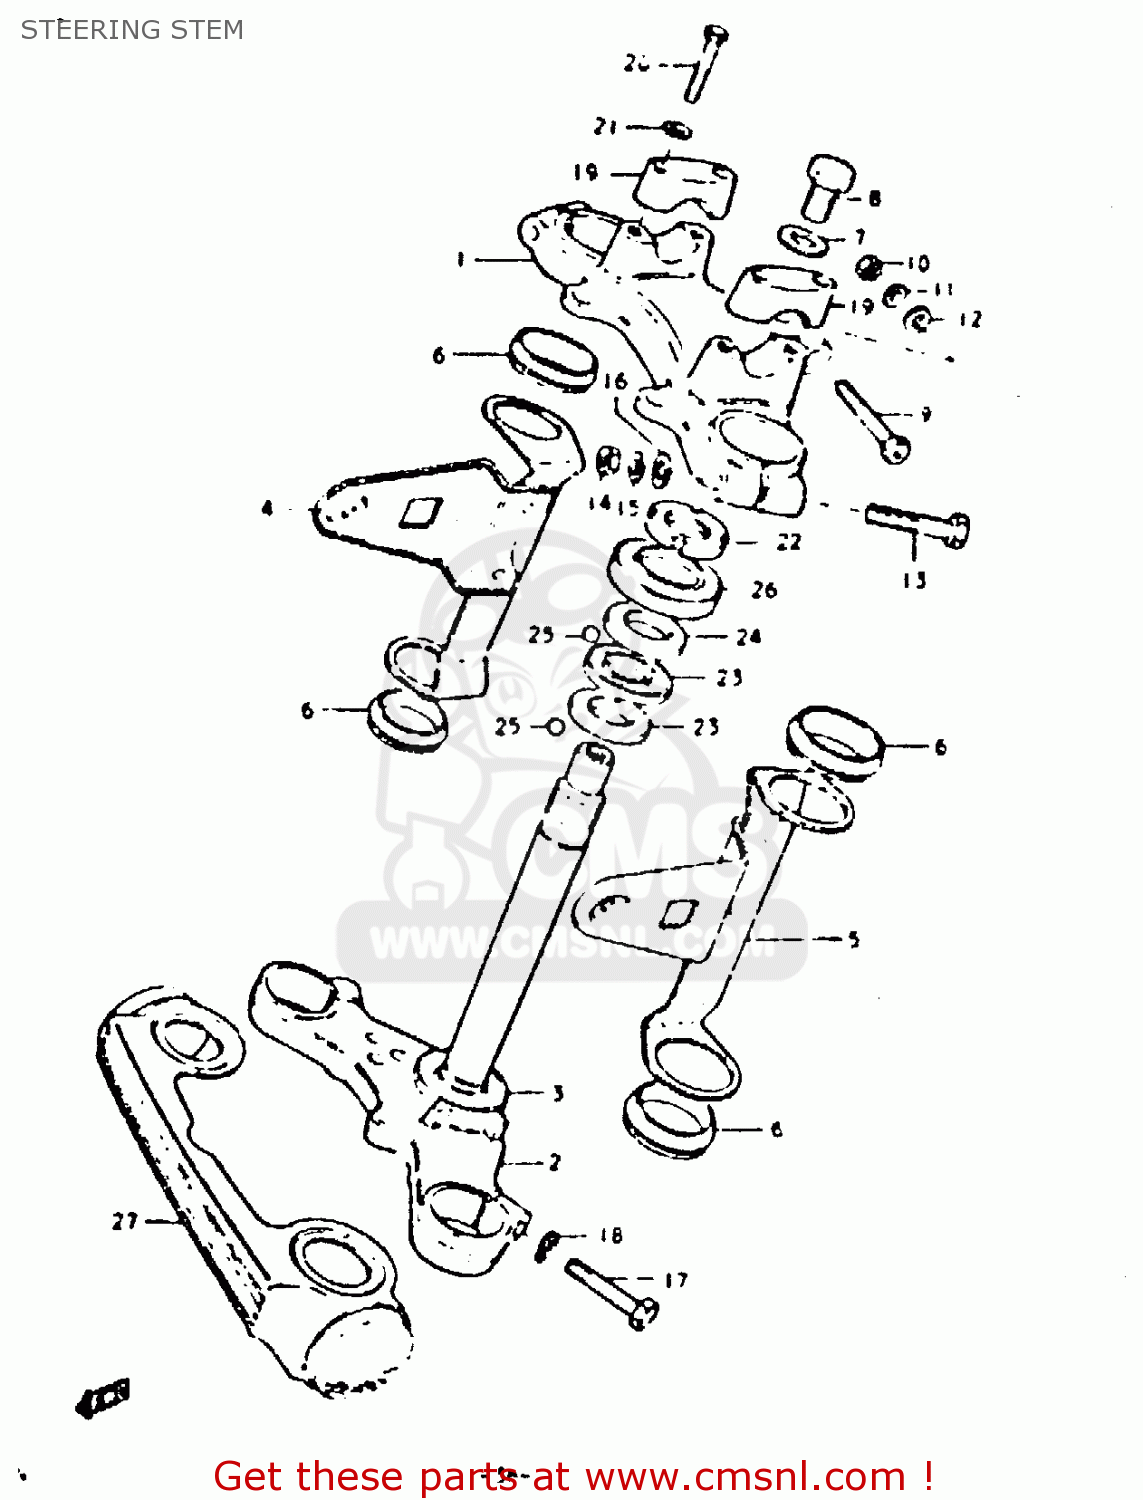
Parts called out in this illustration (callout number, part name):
1	HEAD,STEERING STEM
2	STEM,STEERING
3	RACE,STEERING OUTER LWR
4	BRACKET,HEADLAMP,RIGHT
5	BRACKET,HEADLAMP,LEFT
6	CUSHION,HEADLAMP BRACKET
7	WASHER
8	BOLT(12X20)
9	BOLT
10	NUT
11	LOCK WASHER
12	WASHER
13	BOLT
14	NUT
15	LOCK WASHER
16	WASHER
17	BOLT 10X40
18	LOCK WASHER
19	HOLDER,HANDLE UPR
20	BOLT
21	LOCK WASHER
22	NUT,STEERING STEM(25X44X10)
23	LACE,STEERING INNER LWR
24	LACE,STEERING OUTER UPR
25	BALL
26	DUST SEAL,STEERING UPR
27	COVER,FR FORK
